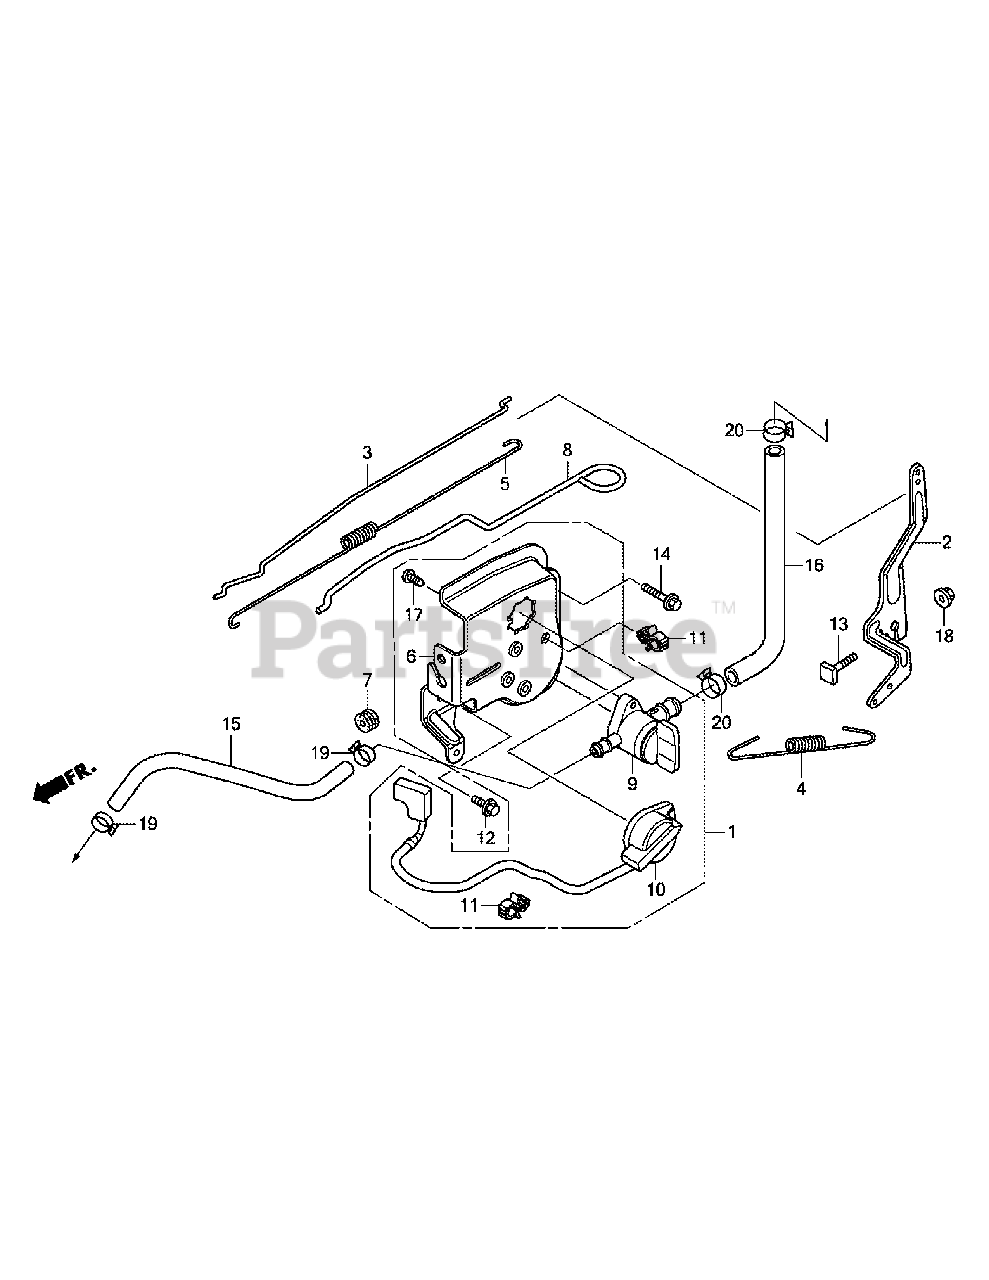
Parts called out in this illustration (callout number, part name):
1	Control Assembly
2	Governor Arm
3	Governor Rod
4	Governor Spring
5	Throttle Return Spring
6	Control Base
7	Choke Rod Grommet
9	Petcock Assembly
10	Engine Stop Switch Assembly
11	Wire Holder
12	Flange Bolt, 6 x 12
13	Governor Arm Bolt
14	Flange Bolt, 6 x 32
17	Screw, 5 x 12
18	Flange Nut, 6mm
